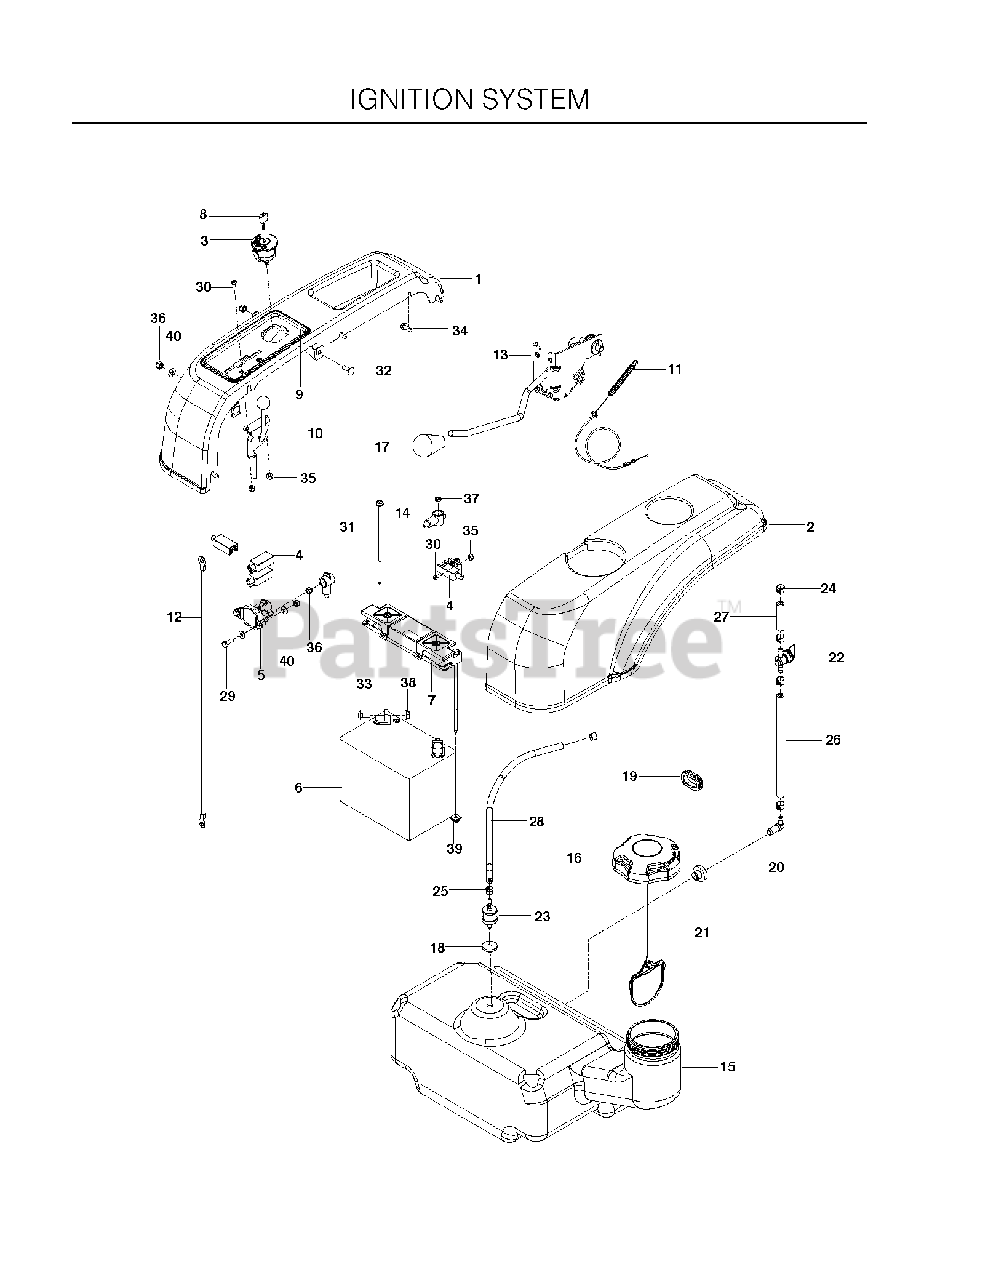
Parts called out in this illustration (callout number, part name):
1	FENDER RH
2	FENDER LH
3	IGNITION SWITCH
4	SWITCH, INTERLOCK
5	SOLENOID
6	BATTERY, 12 V 330 AMP TBR
7	BATTERY HOLD DOWN
8	KEY
9	MOUNT, CONTROLS, BLK
10	CABLE, THROTTLE
11	CABLE.CLUTCH.38".SERVICE
12	BATTERY CABLE, NEGATIVE
13	ASM, CLUTCH ENGAGE W/CABLE
14	TERMINAL COVER-SM
15	TANK, FUEL EPA
16	CAP, FUEL
17	KNOB - SHIFT
18	GROMMET, CHECK VALVE
19	RUBBER GROMMET
20	STEM, FUEL TANK
21	RUBBER GROMMET
22	FUEL VALVE
23	VALVE.FUEL.CHECK
24	HOSE CLAMP
25	CLAMP, HOSE
26	HOSE 1/4 X 8
27	HOSE 1/4 X 2"
28	HOSE.FEEL.3/16" X 20"
29	HCS 1/4C X 3/4 HCS
30	SCREW #10-24 X 5/8
31	BOLT - 1/4-20 X 7.5
32	RHSNB 1/4C X 3/4
33	BOLT 5/16C X 3/4" CARRIAGE
34	SCREW 1/4 X 5/8
35	NUT 10-24 NYLOC
36	NUT 1/4-20 NYLOC
37	JAM NUT 1/4C
38	5/16-18 NYLOC FLANGE NUT
39	PUSH NUT-NYLON
40	WASHER 1/4 SAE
